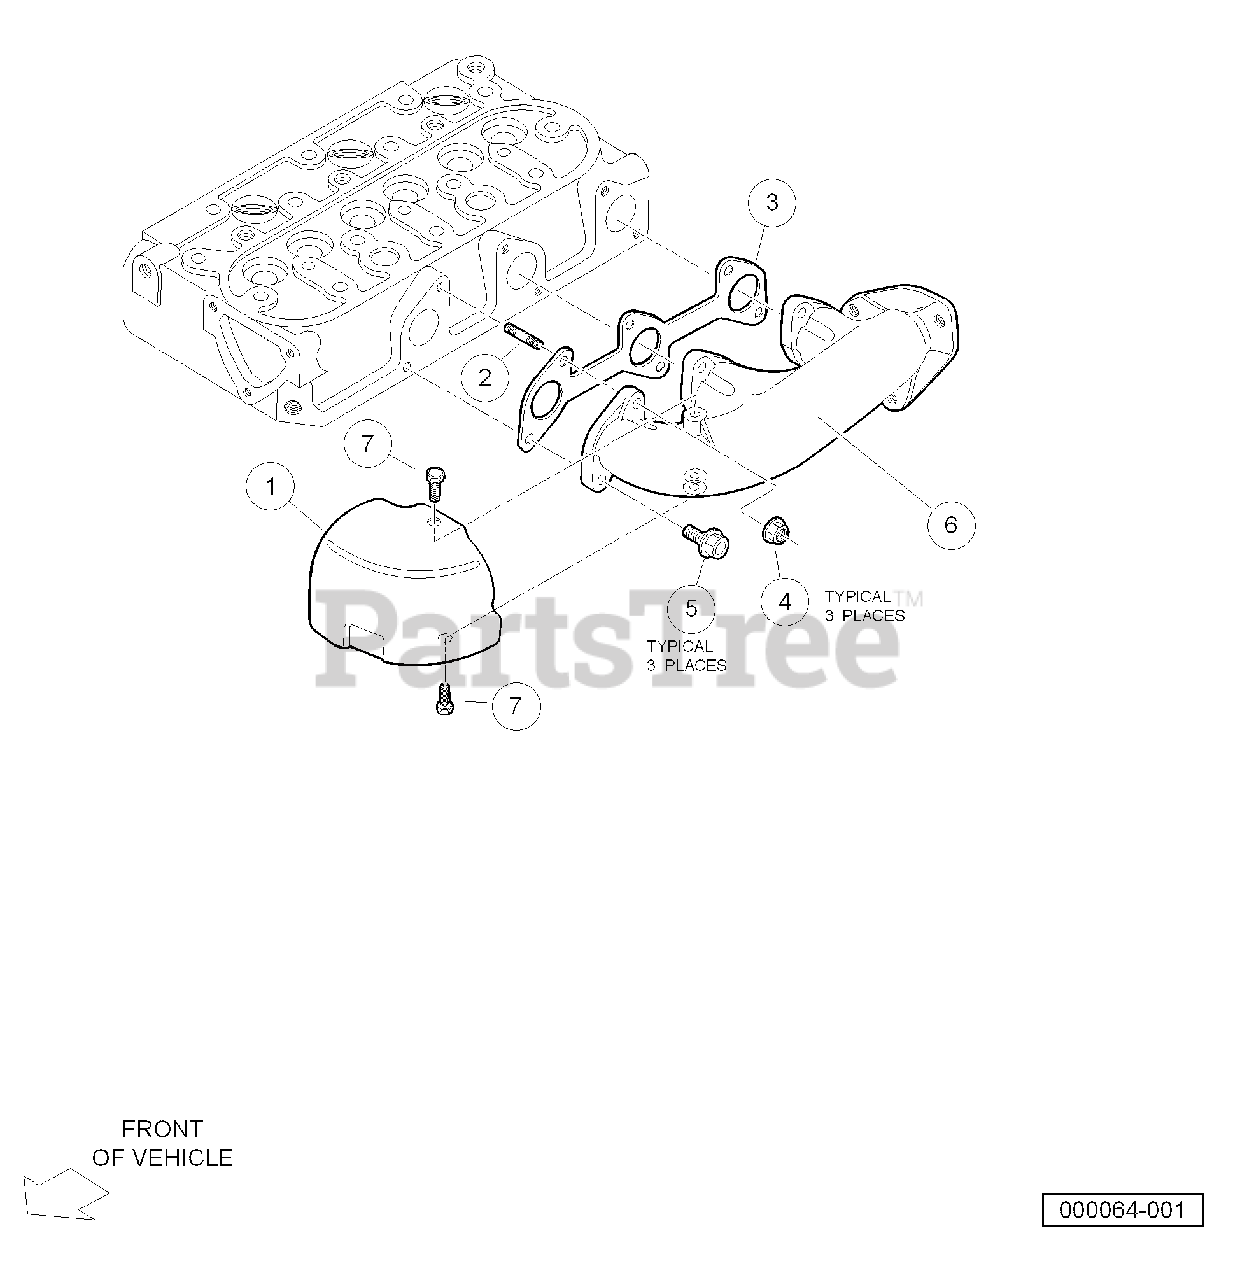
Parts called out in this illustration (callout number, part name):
1	Covgt, Heat Proof
2	Stud, M6 X 26
3	Gasket, Ex-manifold
4	Nut, Flange, M6, Ubs
5	Bolt, Flange Head, M6 X 1 X 16
6	Manifold, Exhaust, D722
7	Bolt, D722, Exhst Manfld Cover
